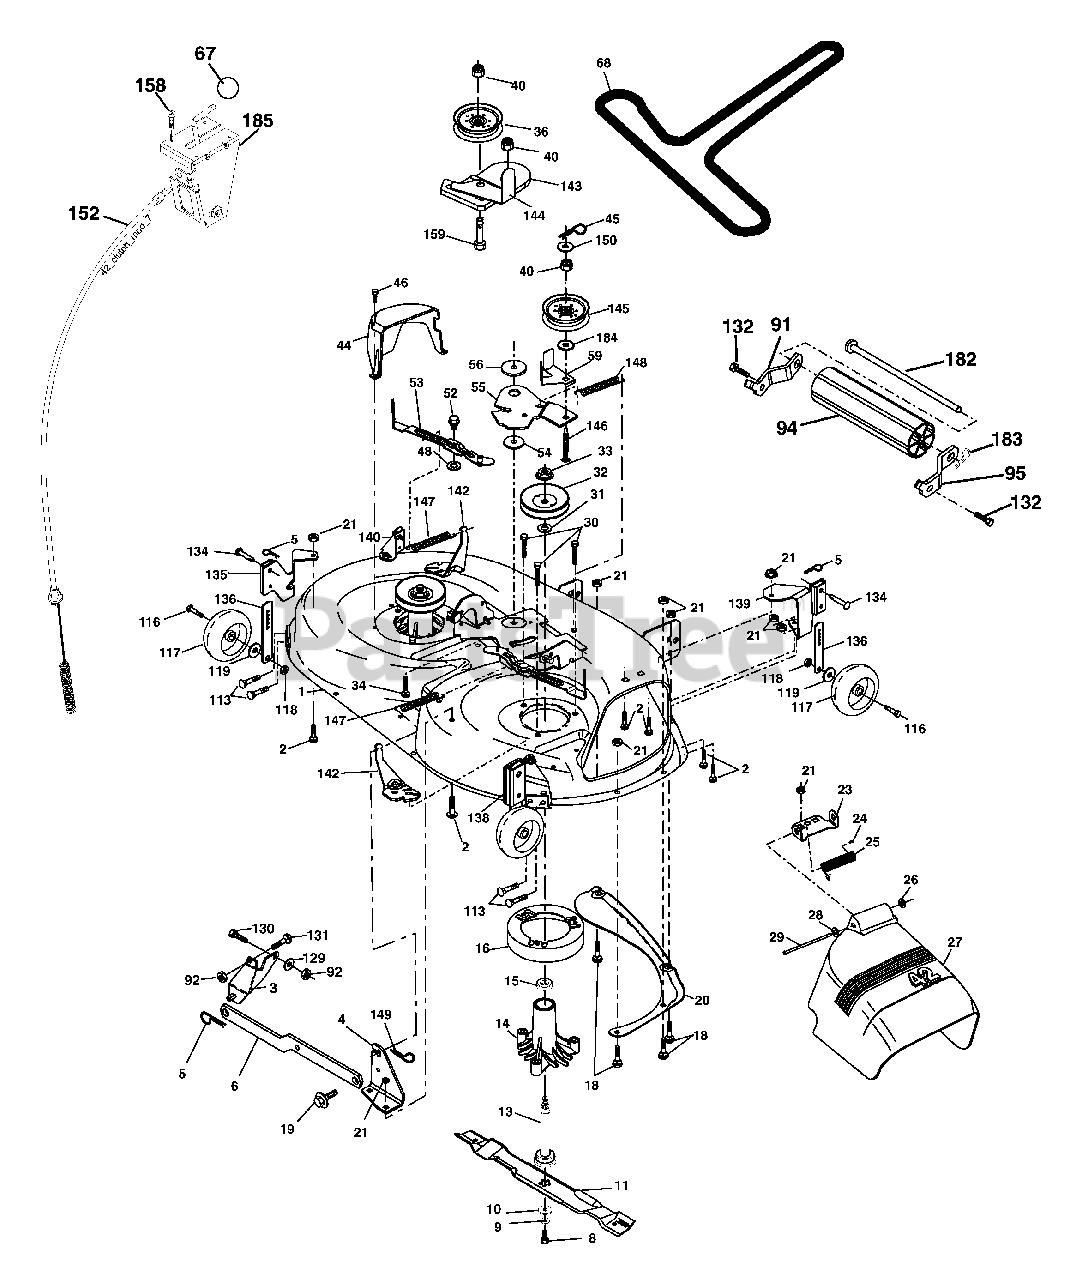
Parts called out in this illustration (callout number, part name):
1	Mower Deck Assembly, 42"
2	Bolt
3	Bracket Asm Fr. Sway Bar 3/42
4	Bracket Asm Deck 42" Sway Bar
5	Retainer Spring
6	Bar Sway Deck
8	Bolt 3/8-24 x 1.25 Gr. 8 patched
9	Washer, Lock
10	Washer, Hardened
11	Blade Mower 42" Hi-Lift
11	Blade, Mulching 42" Std
11	Blade Mulching 42" Premium
13	Shaft Assembly, Mandrel, Vented
14	Housing, Mandrel, Vented
15	Bearing, Ball, Mandrel
16	Stripper, Mandrel Deck
18	Bolt, Carriage 5/16-18 x 5/8
19	Bolt, Shoulder
20	Baffle, Vortex
21	Nut
23	Bracket, Deflector Mower 42"
24	Cap, Sleeve 80 x 112 Blk Mower
25	Spring, Torsion, Deflector 2 52
26	Nut, Push Phos & Oil
27	Shield, Deflector 42" Blk
28	Washer 11/32 x 5/8 x 16 Ga.
29	Rod, Hinge 42" 6 75 W/G
30	Screw Thdrol
31	Washer, Spacer Mower Vented
32	Pulley, Mandrel
33	Nut, Toplock
34	Bolt Carr SH 3/8-16 x 1-1/2 Gr.5
36	Pulley, Idler, Flat
40	Nut Lock 3/8-16
44	Guard, Mandrel, LH
45	Retainer
46	Screw, Thdrol 1/4-20 x 5/8 T
48	Washer Hardened
52	Bolt Shld 5/16-18
53	f Arm Asm Brake
54	Washer, Hardened
55	Arm, Idler
56	Spacer, Retainer
59	Guard TUV Idler
67	Knob
68	V-Belt, 42" Mower
91	Bracket Nose Roller LH
92	Nut Lock W/Ins 3/8-16 unc
94	Roller Nose
95	Bracket Nose Roller RH
113	Screw 5/16-18
116	Bolt, Shoulder
117	Wheel, Gauge
118	Nut Centerlock 3/8-16
119	Washer 3/8 x 7/8 x 14 Ga.
129	Washer 13/32 x 13/16 x 12 Ga.
130	Bolt Fin HEx 3/8-16 unc x 1 Gr. 5
131	Bolt RDHD SQNK 3/8-16 unc x 1
132	Screw Hexwsh Thdr. 3/8-16 x 3/4
134	Pin Head Rivet
135	Bracket Asm Wheel Ga. Rear LH
136	Bar Adjusting Gauge Wheel
138	Bracket Asm Wheel Ga. Rear RH
139	Bracket Asm Wheel Ga. Front RH
140	Bracket Asm Wheel Ga. Front LH
142	Arm Spring Brake Mower
143	Bracket Arm Idler 42"
144	Keeper Belt 42" Clutch Cable
145	Pulley Idler Flat
146	Bolt Carriage Idler
147	Spring Extention
148	Spring Return Idler
149	Retainer Spring Yellow
150	Washer 9/32 x 3/4 x 10 Ga.
152	Cable Clutch
158	Screw Thd Cut 1/4-20 x 1/2
159	Bolt Rdhd Sqn 3/8-16 unc x 1-3/4
182	Rod Roller Nose
183	Retainer Spring
184	Washer 13/32 x 7/8 x 10 Ga.
185	Head Asm. Cable Clutch
